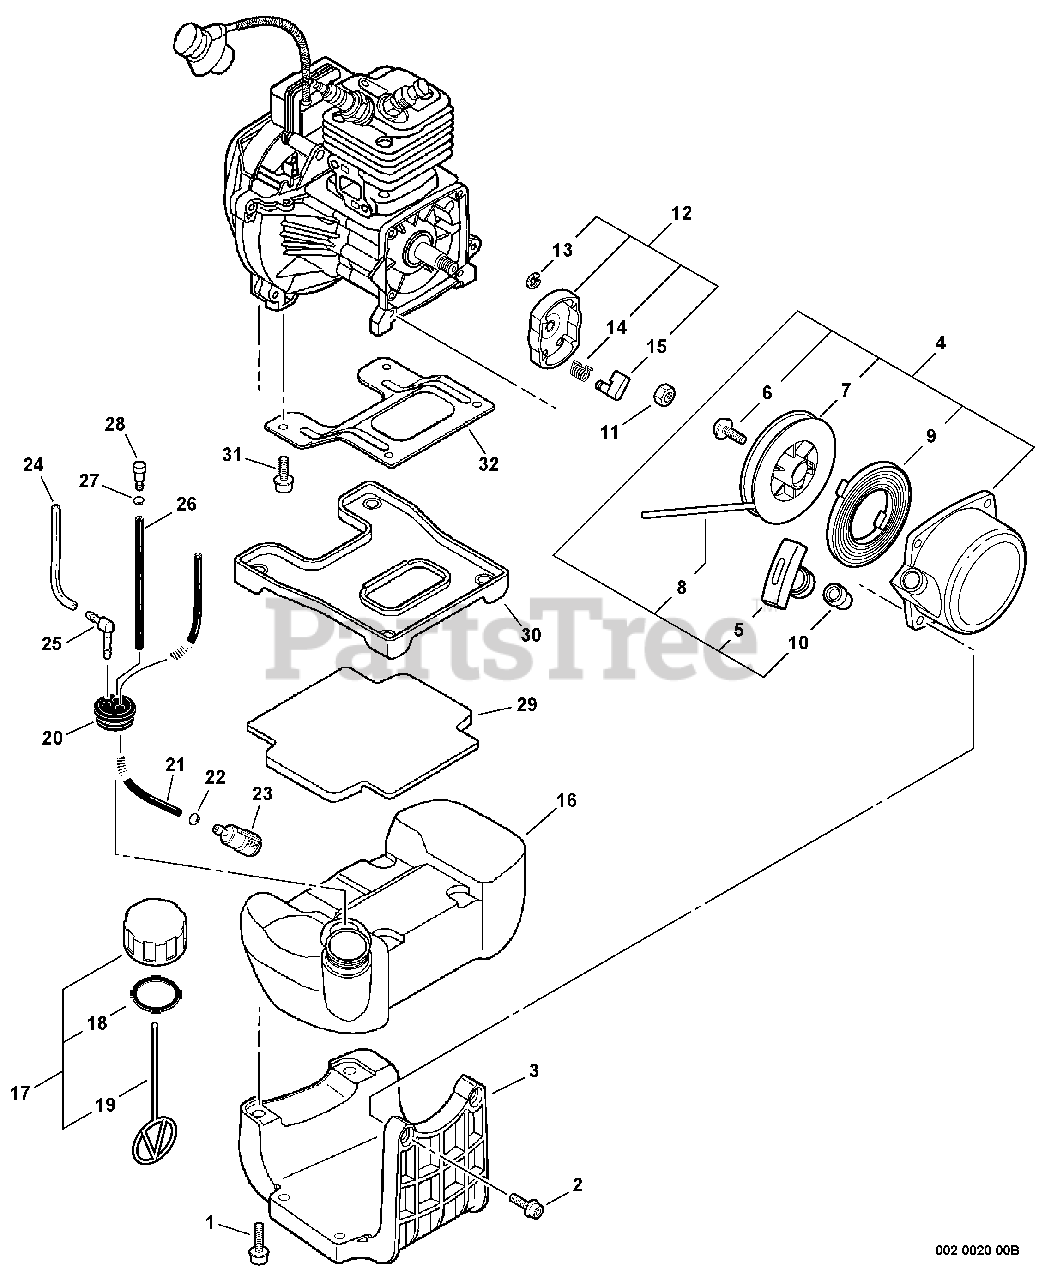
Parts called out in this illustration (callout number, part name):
1	BOLT 5×20
2	BOLT 5×25
3	GUARD, FUEL TANK
4	STARTER ASSY, RECOIL
5	GRIP, STARTER
7	REEL, ROPE
8	ROPE, STARTER 3.8×1150
9	SPRING, RECOIL
10	GUIDE, ROPE
11	NUT 8×1.25
12	PULLEY ASSY, STARTER
13	E-RING 4
14	SPRING, RETURN
15	PAWL, STARTER
16	TANK, FUEL
17	CAP ASSY, FUEL
18	GASKET, FUEL CAP
19	CONNECTOR, CAP L= 100 MM
20	GROMMET, FUEL
21	PIPE, FUEL 3×6×180 BLACK
22	CLIP Ø6.5 MM
23	FILTER, FUEL
24	PIPE, FUEL 3×6×60 CLEAR
25	CONNECTOR, PIPE Ø5.4
26	PIPE, FUEL 3×6×120 BLACK
27	CLIP Ø6.5 MM
28	VENT ASSY
29	CUSHION, FUEL TANK
30	CUSHION, UPPER
31	BOLT 5×12
32	BRACKET, FUEL TANK
